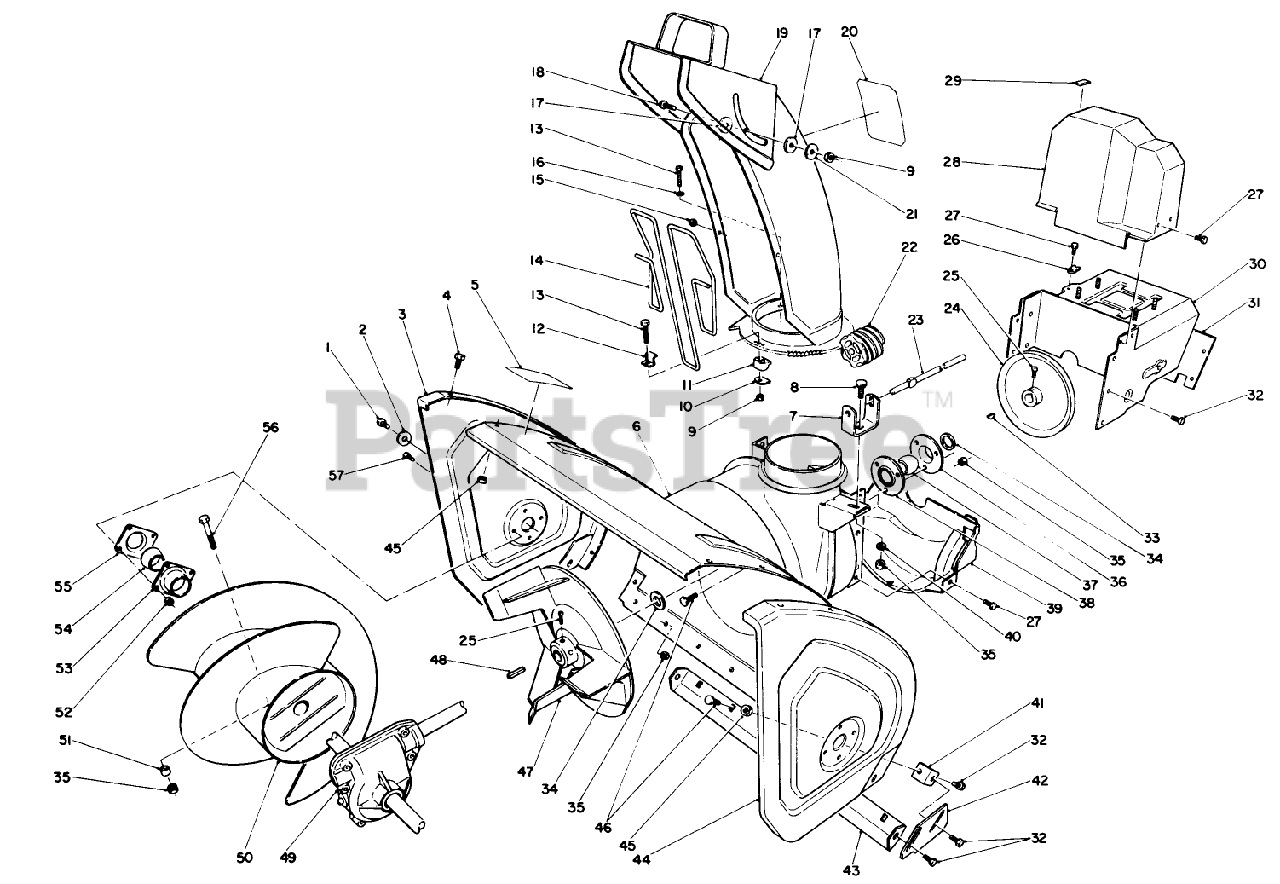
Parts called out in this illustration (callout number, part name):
1	SCREW-HH
2	WASHER
4	SCREW-HHF
7	BRACKET-WORM, CHUTE
8	BOLT-CARR
9	NUT-LOCK, NI
10	PLATE-RETAINER, CHUTE
11	RETAINER-CHUTE
12	CLIP-GUARD, CHUTE
13	SCREW-HSH
14	GUARD-CHUTE
15	NUT-PUSH
16	WASHER-FLAT
17	WASHER-PLASTIC
21	WASHER-FLAT
22	GEAR-WORM
23	ROD-CHUTE, LOWER
25	SCREW-SET, SQH
26	RETAINER-CABLE
27	SCREW-HWH
28	COVER-BELT, UPPER
29	COVER-CABLE
32	SCREW-HHF
33	KEY-WOODRUFF
34	WASHER-THRUST
35	NUT-LOCK, NI
36	FLANGE-CUP, BEARING
37	BEARING-BALL
38	FLANGE-CUP, BEARING
40	WASHER-PLAIN
44	L/H SIDEPLATE *R
45	NUT-LOCK, NI
46	SCREW-CARR
49	GEARCASE ASM - AUGE
51	SPACER-HUB, AUGER
52	NUT-LOCK, CONE
53	BEARING-FLANGE, FRONT
54	BEARING
55	BEARING-FLANGE, REAR
57	SCREW-HH
